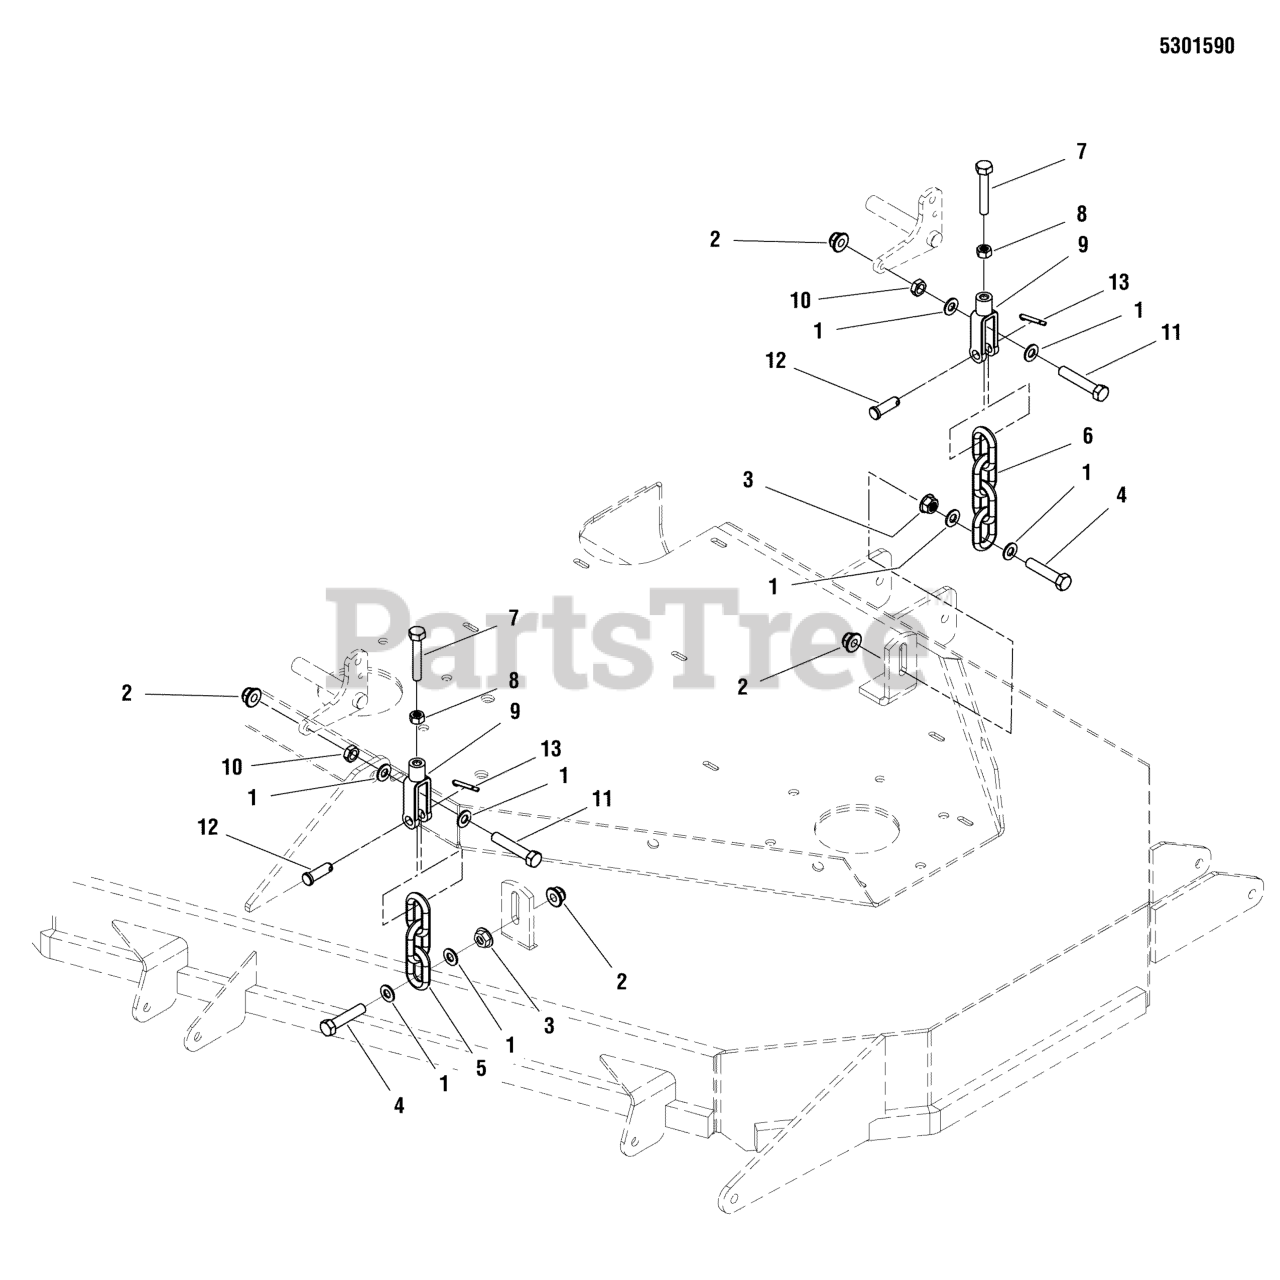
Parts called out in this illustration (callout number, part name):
1	WASHER, 3/8 SAE
2	NUT, 3/8-16 HEX NYLOCK FLANGE
3	NUT, 3/8-16 HEX SERRATED FLANGE
4	BOLT, 3/8-16 X 1-3/4" GD5 CZ
5	CHAIN, 5/16 GD30, 3 LINKS
6	CHAIN, 5/16" GD30, 4 LINKS
7	BOLT- 5/16-18 X 1-3/4 GD5 TFL
8	NUT, 5/16-18 HEX
9	CLEVIS, 5/16-18, 3/8 PIN HOLE
10	NUT, 3/8-16 HEX JAM
11	BOLT, 3/8-16 X 2, GD5, CZ
12	PIN, CLEVIS, 3/8 X 1-1/8
13	PIN, 3/32 X 0.750, COT, ZINC/CLEAR
